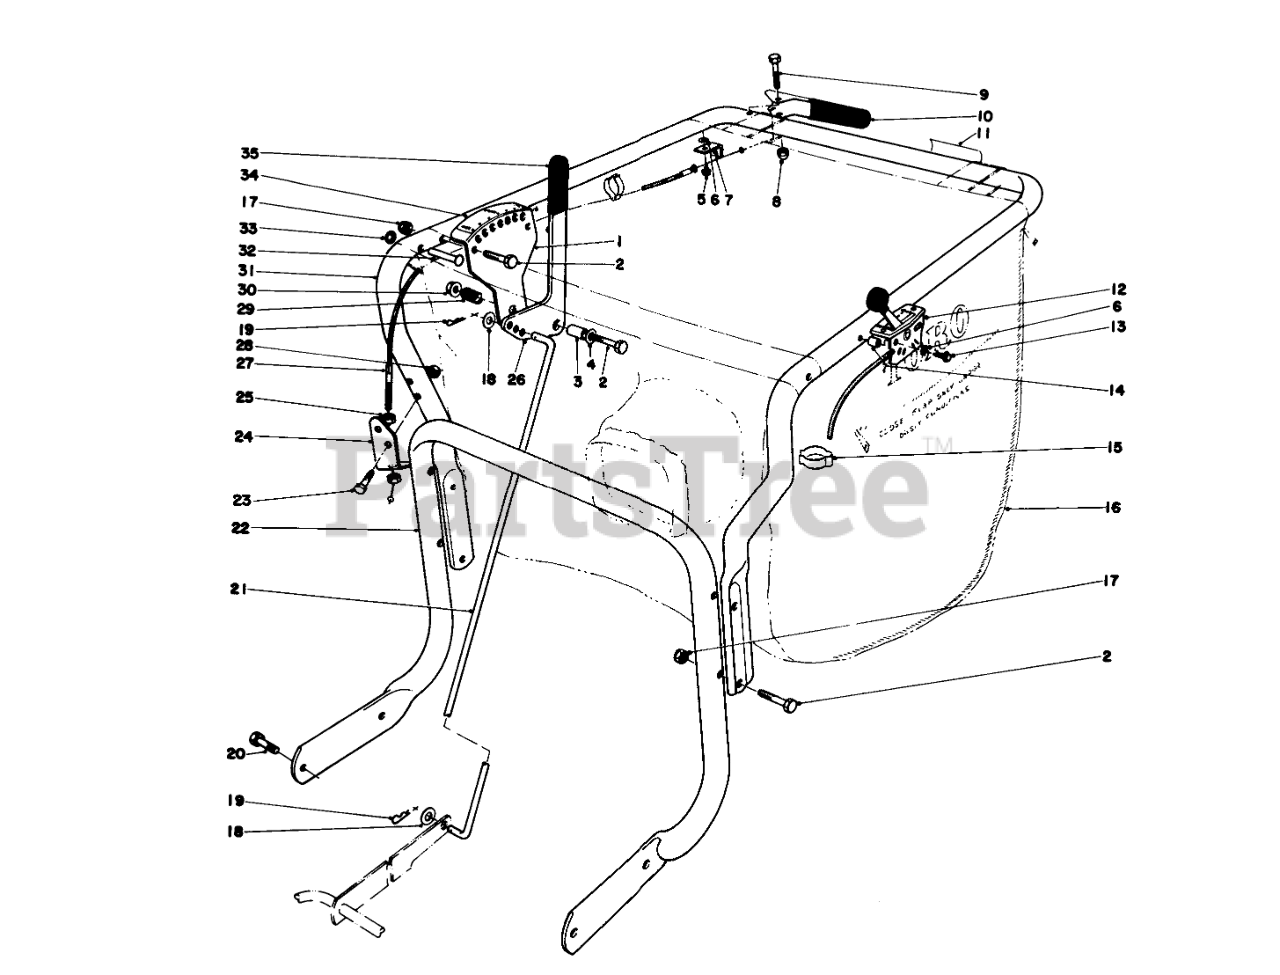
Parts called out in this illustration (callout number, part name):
1	Adjustment Bracket
2	SCREW-HH
3	SPACER
4	WASHER-FLAT
5	SCREW
6	WASHER-LOCK, EXT
7	RETAINING-CLIP
8	NUT-CAP
9	SCREW-HH
10	LEVER W/GRIP
11	TRACTION CONT DECAL
12	THROTTLE CONTROL
13	10-24 X 1 PAN HD SCR
14	SPACER
15	BODEN CLIP
16	Bag-Vacuum
17	NUT-LOCK, CONE
18	WASHER-FLAT
19	PIN-COTTER
20	SCREW-HH
21	HEIGHT ADJ. ROD
22	HANDLE
23	SCREW-HH
24	MOUNT-BOWDEN, LOWER
25	NUT-KEPS
26	Handle-Adjustment
27	FWD ASSY CABLE
28	NUT-LOCK, CONE
29	SPRING-COMPRESSION
30	NUT-HF
31	HANDLE-UPPER, VACUUM
32	RIVET
33	NUT-PUSH IN
34	HT ADJ DECAL
35	GRIP-HANDLE
